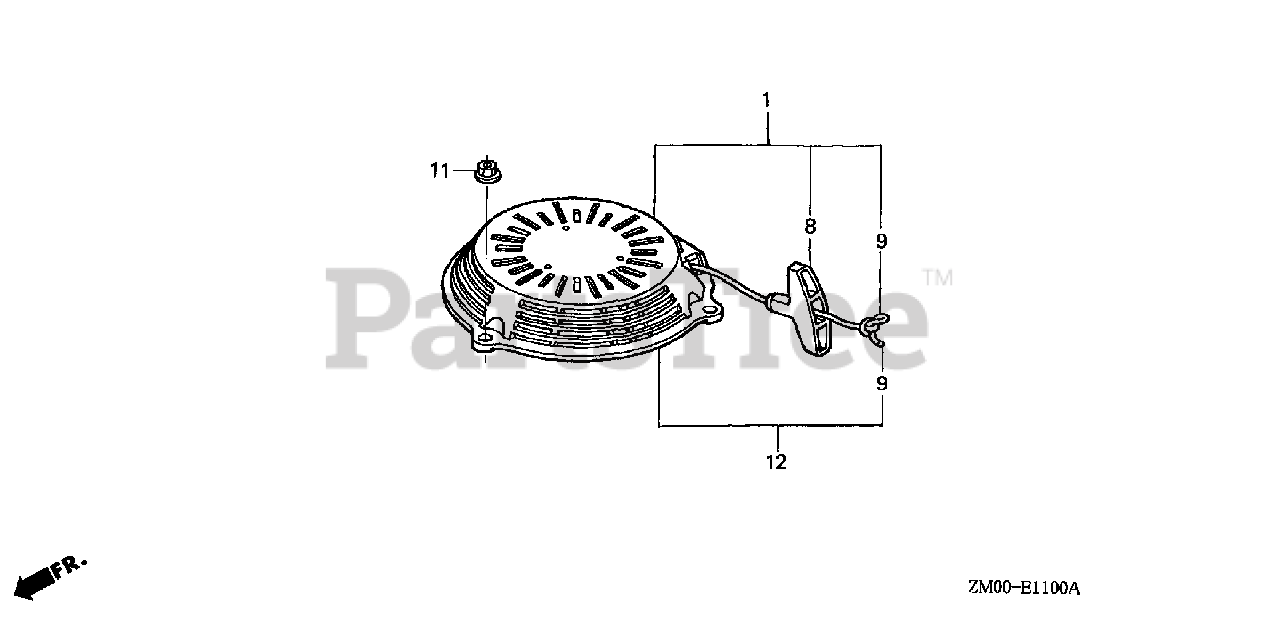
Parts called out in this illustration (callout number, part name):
1	STARTER ASSY., RECOIL *NH1* (LONG ROPE) (BLACK)
8	KNOB, RECOIL STARTER
9	ROPE, RECOIL STARTER
11	NUT, FLANGE (6MM)
